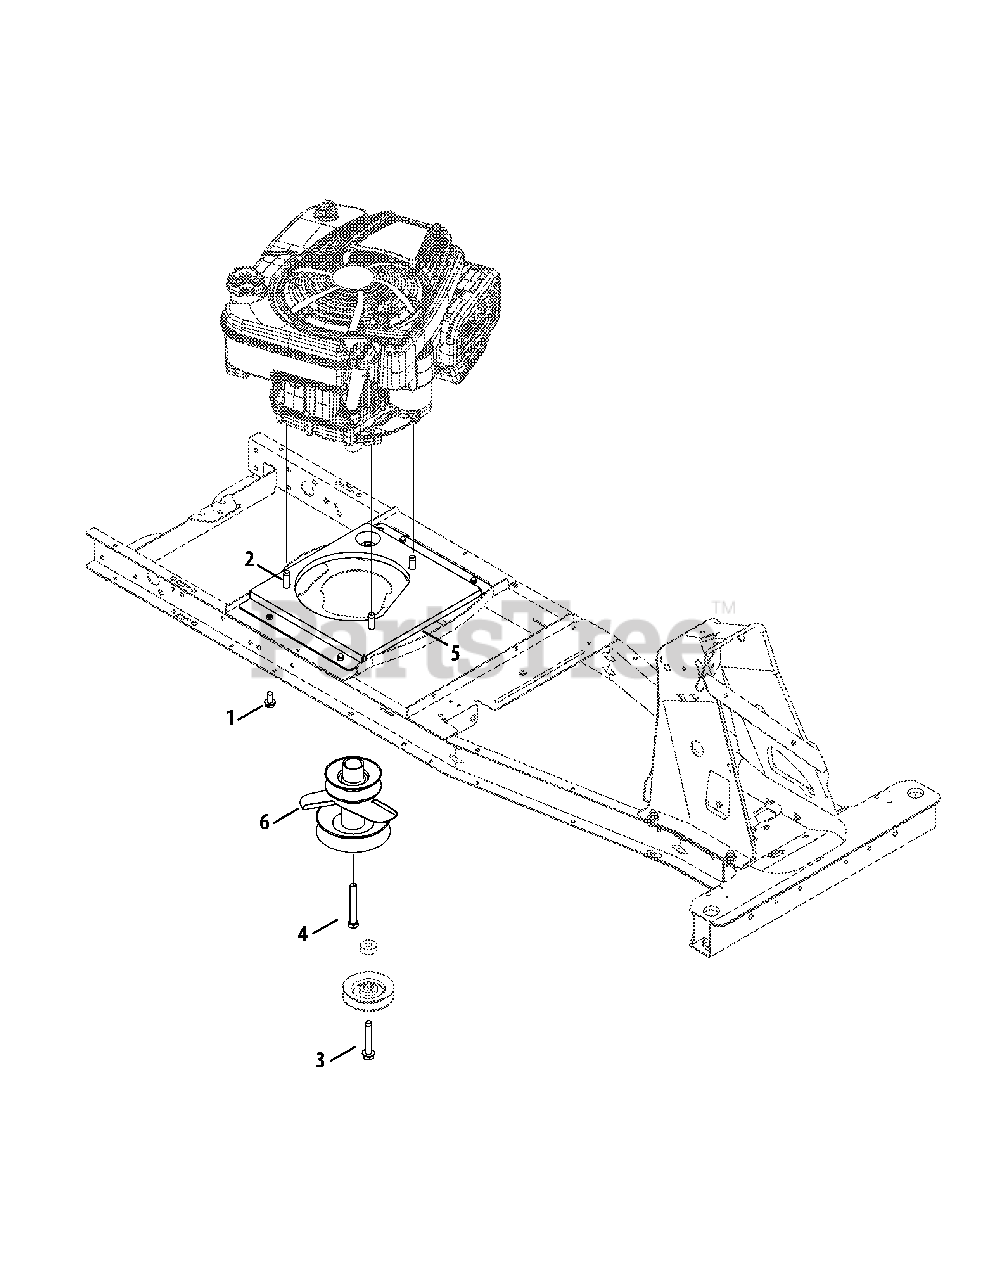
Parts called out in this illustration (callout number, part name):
1	Tap Screw, 5/16-18, .750
2	Tap Screw, 3/8-16, 1.000
3	Tap Screw, 3/8-16, 2.250
4	Hex Cap Screw, 3/8-24 x 2.75
5	Engine Mounting Plate
6	Engine Pulley
